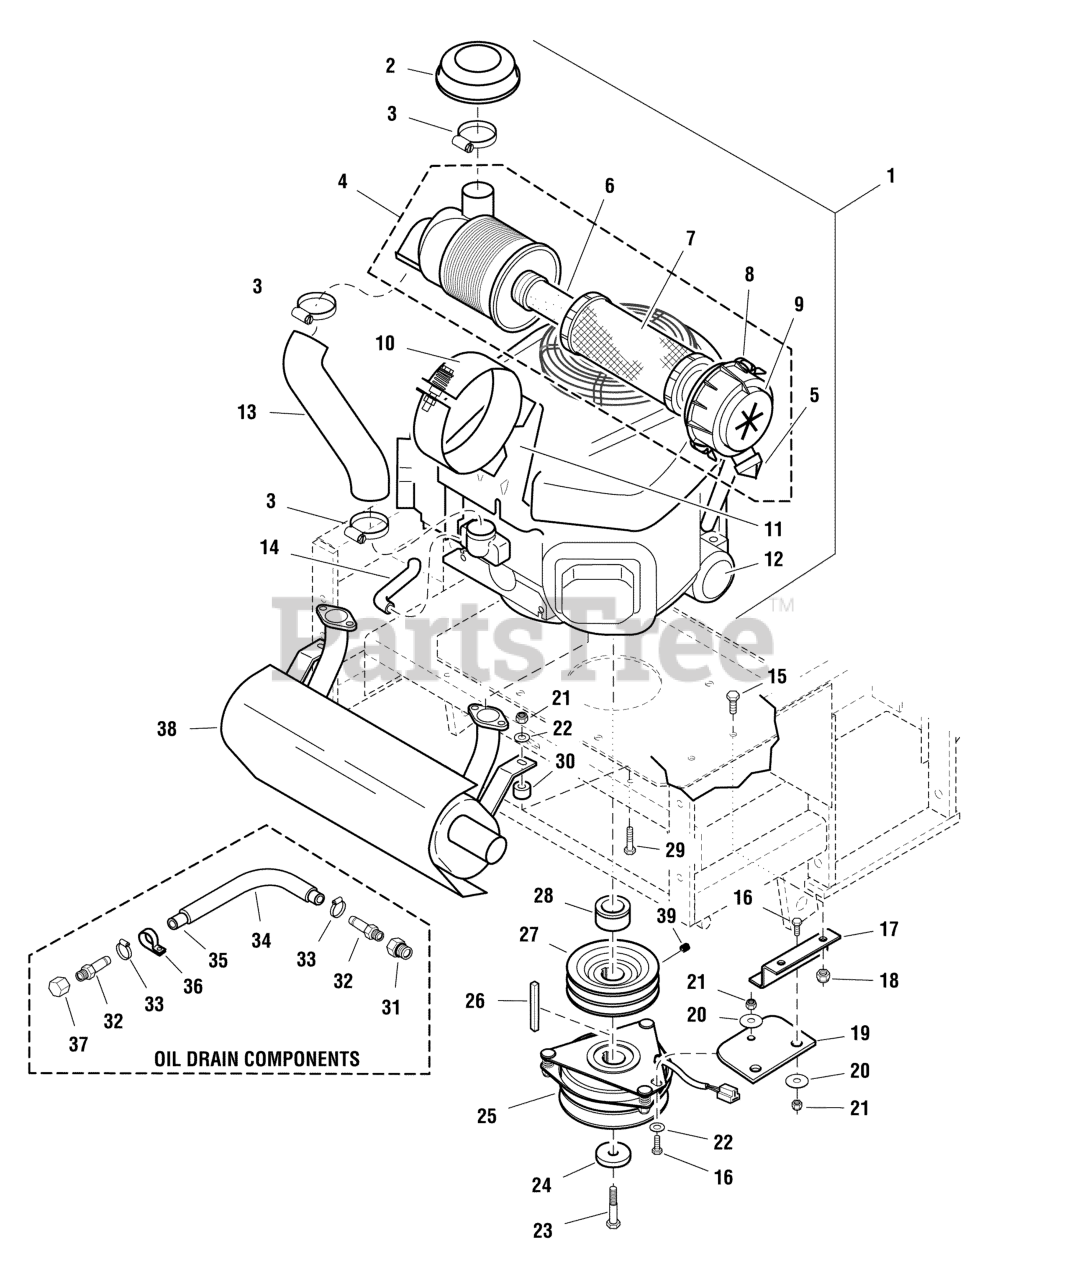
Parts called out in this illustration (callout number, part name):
2	RAIN CAP
4	AIR FILTER ASSEMBLY, Complete
5	RUBBER, Dust Valve
6	AIR FILTER, Secondary
7	AIR FILTER, Primary
8	CLAMP, Cap
9	CAP, FIlter Case
10	CASE BRACKET, Complete
11	BRACKET PLATE
12	OIL FILTER (49065-2078)
13	AIR INLET TUBE
14	BREATHER TUBE
15	BOLT, 3/8-16 X 1" GD5 CZ
16	BOLT, 5/16-18 X 3/4 GD5
17	ANCHOR, CLUTCH - BLK
18	NUT, 3/8-16 HEX NYLON LOCK
19	CLUTCH ANCHOR PAD
20	WASHER, 3/8" Fender
21	NUT, 5/16-18 Hex Nylon Lock
22	WASHER, 5/16" SAE
23	CRANKSHAFT BOLT, 7/16 x 2-1/4
24	SPACER, .45 x 1.88 x .38
25	ELECTRIC CLUTCH
26	KEY, 1/4 SQ. X 3
27	CRANKSHAFT PULLEY
28	SPACER, 1.13 x 1.75 x 1.03
29	BOLT, 5/16-18 x 1-1/2
30	SPACER, .39 x 1.00 x .80
31	ADAPTER, Oil Drain
32	FITTING, 3/8NPT-1/2" Hose, Straight
33	CLAMP, #6 Hose
34	WIRE LOOM, 12"
35	HOSE, 14"
36	CLAMP, Vinyl
37	CAP, 3/8 NPT
38	MUFFLER, 21HP-25HP KAWASAKI ENGINES
39	SET SCREW, 5/16-18 X 3/8, KNURL, W/PATCH
